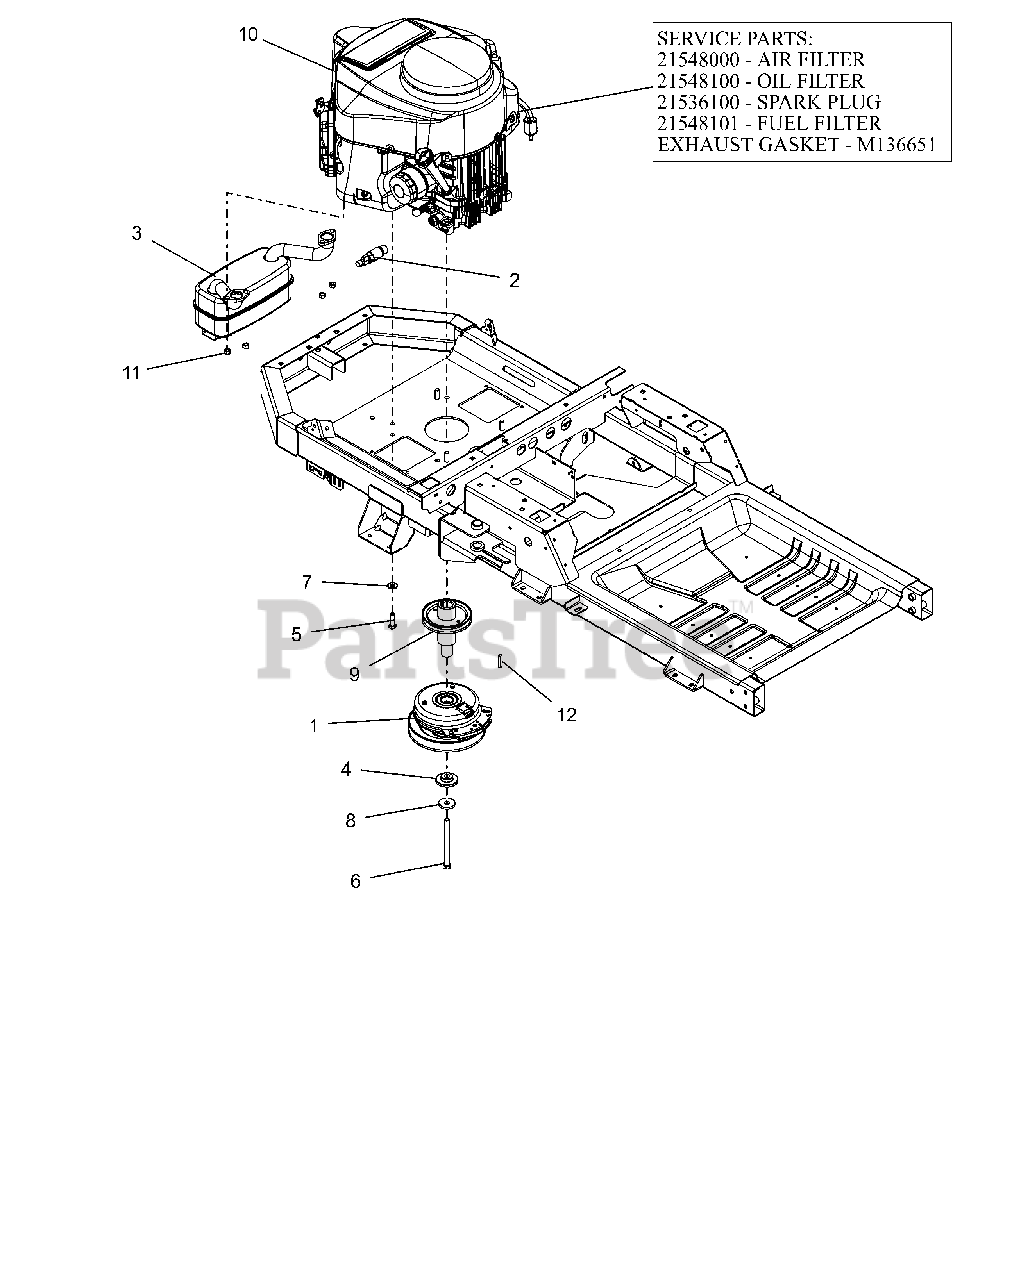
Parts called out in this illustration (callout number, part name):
1	CLUTCH,105FTLB MONOPOLE 6.83"
2	DRAIN, OIL M20X2.5
3	MUFFLER - KAWASAKI
4	BSHG-FLG .469X1.06X.574X2.0
5	BLT-HEX.38-16X1.25 G5YZ NYTORQ
6	BLT-HEX.438-20X5 GR8 YZ NYTORQ
7	WASHER, 3/8" SPRING DISC
8	WASHER, 7/16" SPRING DISK
9	WLDMT, DRIVE SHEAVE (LG XL)CZC
10	ENGINE, KAWASAKI FR691 23HP
10	AIR FILTER, KAWASAKI FR
10	OIL FILTER, KAWASAKI FR
10	PLUG, SPARK
10	FUEL FILTER-KAWASAKI FR
10	GASKET, MUFFLER #
11	NUT-LK-TOP M8-1.25 YWZC
12	KEY-SQ .25 X 1.25 X .25 SAE
